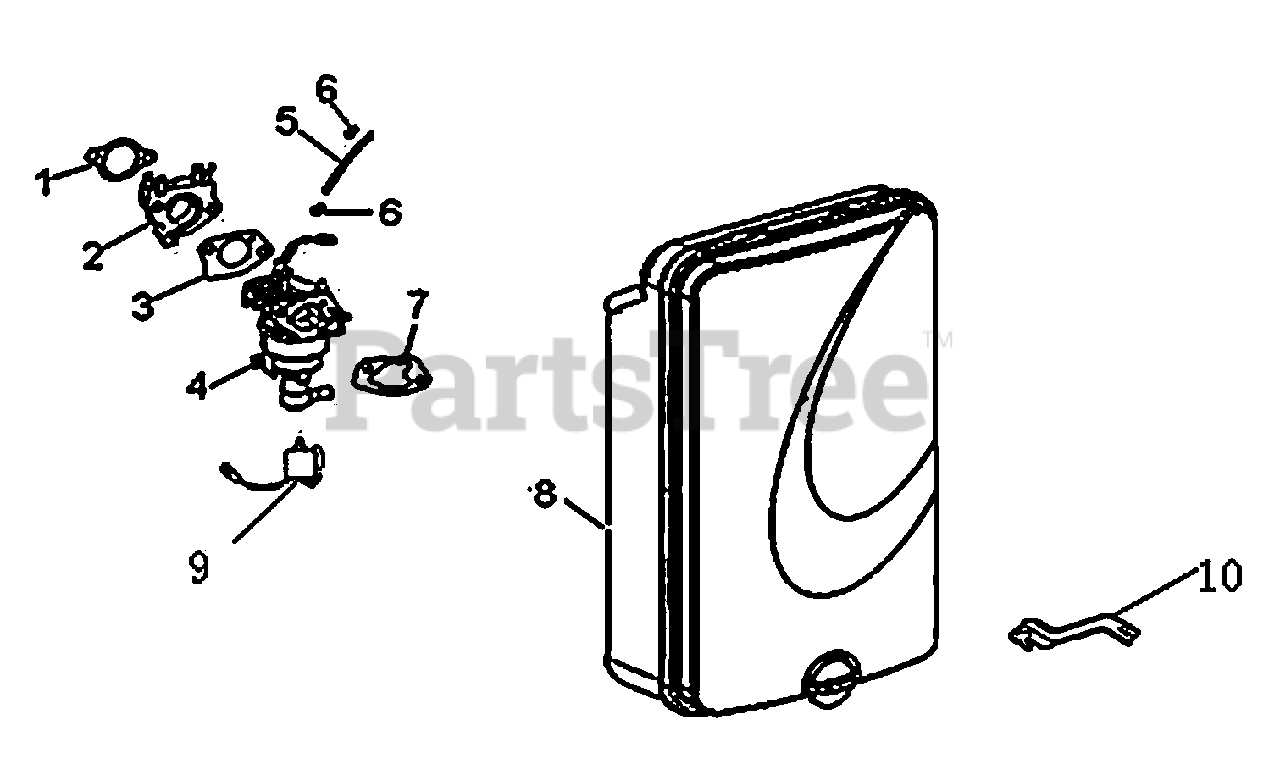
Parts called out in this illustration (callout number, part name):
1	GASKET, INSULATOR
2	SPACER, CARBURETOR
3	GASKET, CARBURETOR
4	CARBURETOR ASSY
5	TUBE,FUEL
7	GASKET, CARBURETOR
8	CLEANER, AIR
9	SOLENOID, THROTTLE CONTROL
10	BRACKET, AIR CLEANER
